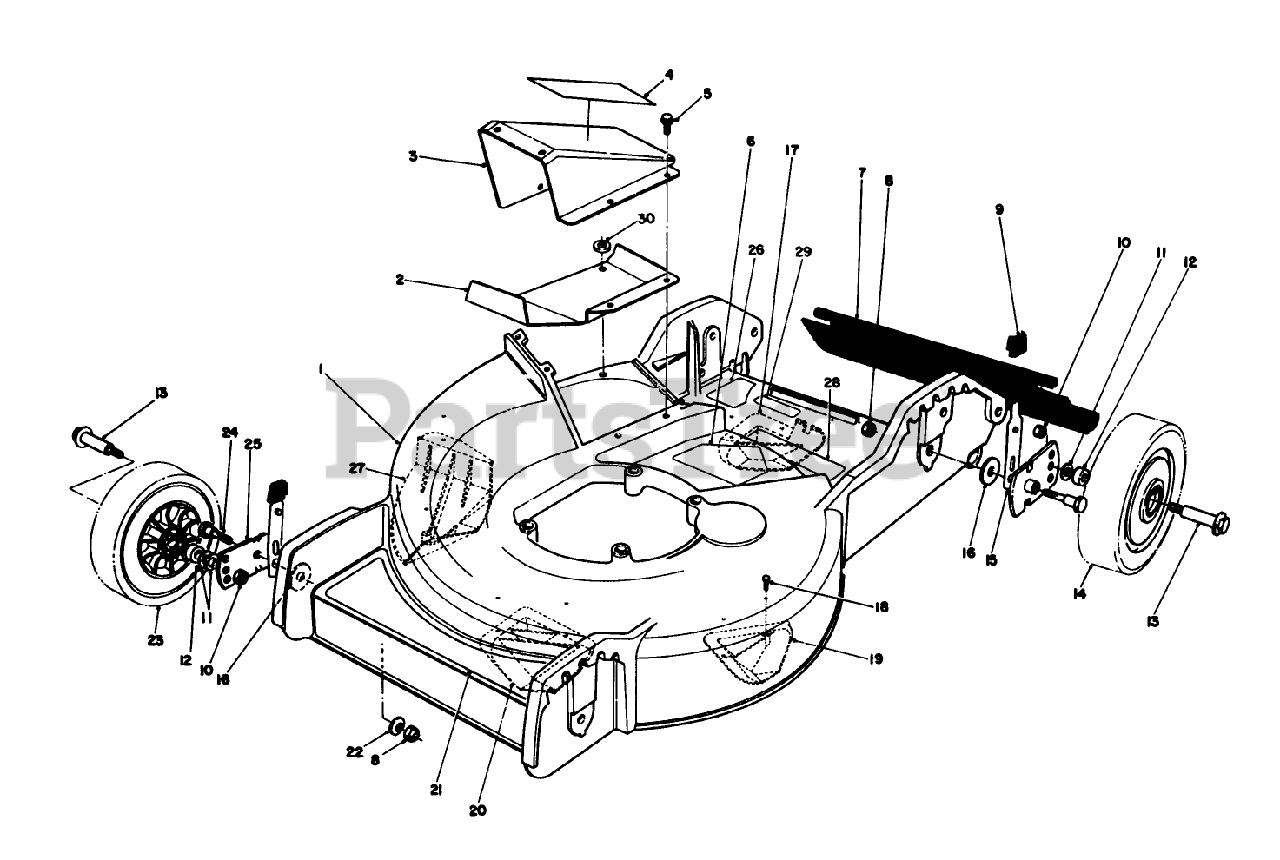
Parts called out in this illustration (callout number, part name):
1	HSG W/DECAL & KICKERS
2	DISCHARGE KICKER*
3	COVER W/DECAL
4	DECAL - COVER
5	SCREW
6	DECAL-DANGER
7	SHIELD - TRAILING
8	NUT-LOCK, NI
9	KNOB-ARM
10	NUT-HEX
11	WASHER
12	SPACER-PLASTIC
13	BOLT-WHEEL
15	SPRING ARM ASM
16	PIVOT WASHER
17	KICKER
18	SCREW-THD ROLL, HWH
19	KICKER
20	KICKER
22	WASHER-BELLEVILLE
23	7" WHL & TIRE ASM
24	5/16-18 PIVOT SCREW
25	PIVOT ARM ASSY
26	DECAL - DANGER
28	DECAL-INSTRUCTION, SAFETY
29	DECAL-WARNING
30	WASHER-FLAT
